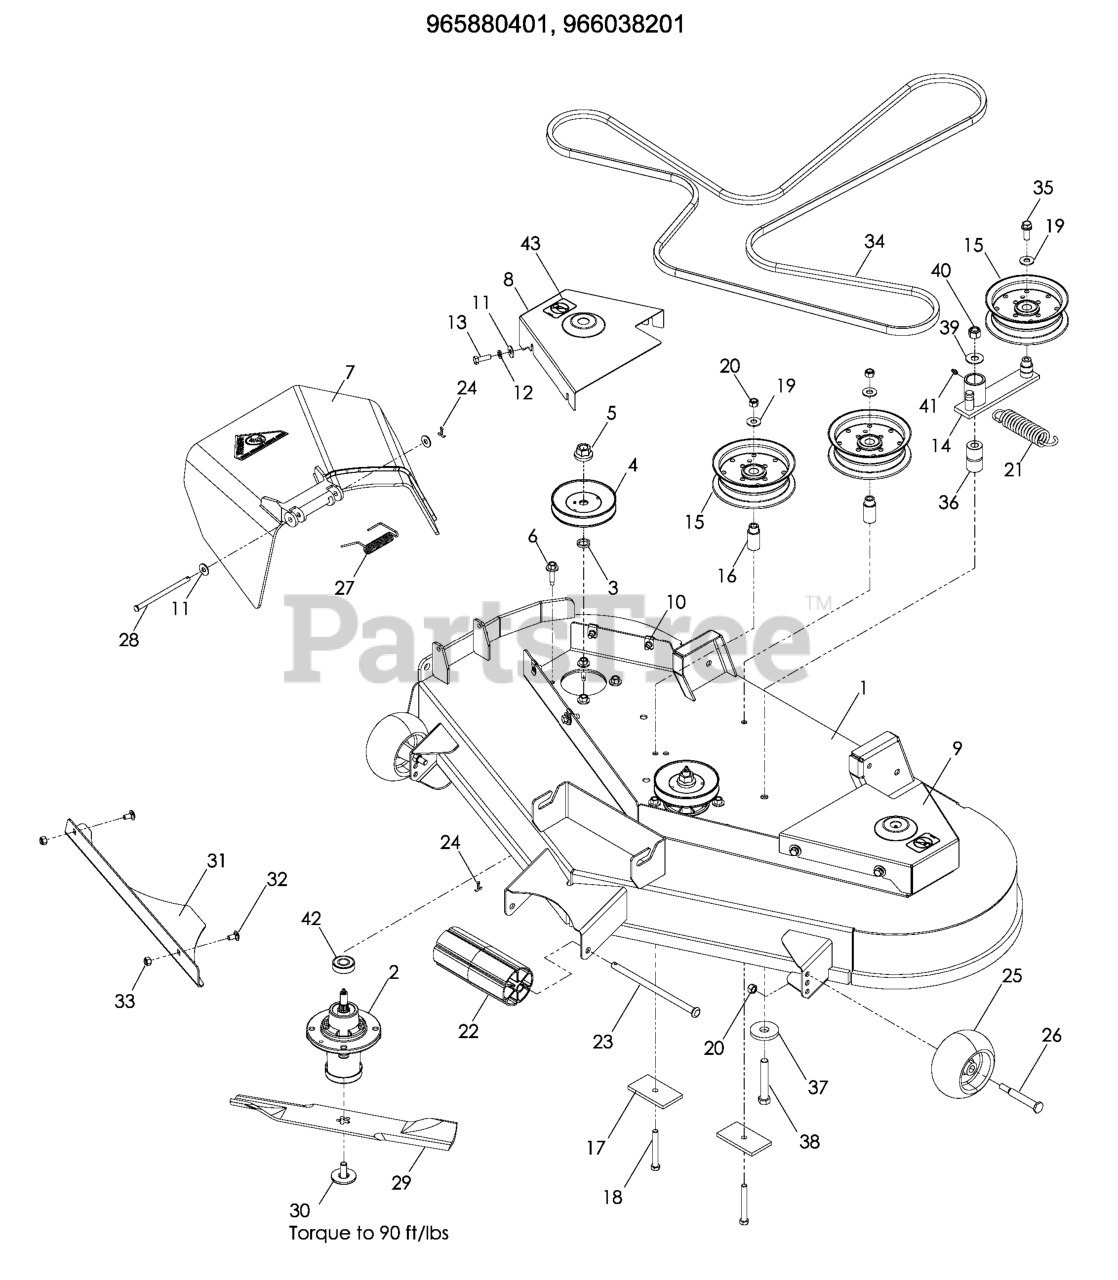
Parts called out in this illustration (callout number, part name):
1	DECK.48".TRI-FORCE.W/DECALS.OR
2	MANDREL.DECK.ASSEMBLY
3	WASHER-SPACER
4	PULLEY MANDREL
5	LOCKNUT - 9/16
6	WASHER HEAD SCREW
7	DISCHARGE CHUTE 48"
8	BELT SHIELD - R.H. ORANGE
9	BELT SHIELD - L.H. ORANGE
10	U-CLIP 5/16-18 NUT RETAINER
11	WASHER 5/16 FLAT
12	WASHER.LOCK.HVY.HLCL.SPR.5/16
13	HCS 5/16C X 3/4
14	PULLEY - IDLER, NYLON
15	PULLEY, IDLER
16	IDLER BUSHING
17	SUPPORT PLATE
18	HCS 3/8C X 3
19	WASHER 3/8 FLAT
20	NUT 3/8-16 NYLOC
22	NOSE ROLLER 48"
23	NOSE ROLLER ROD
24	RP_COTTER PIN 1/8 X 3/4
25	GAUGE WHEEL
26	SHOULDER BOLT 1/2X2-5/8 ZD SPE
27	SPRING - TORSION
28	PIN-CLEVIS 5/16 DIA X 5.19 ZD
29	BLADE, 16-1/4"
30	BLADE BOLT ASSY-7/16" TB REPL
31	CONFINEMENT PLATE 48" BLK
32	CARRIAGE BOLT 5/16C X 5/8"
33	NUT 5/16 NYLOC
34	BELT, DECK
35	4CS 3/8C X 1 SERRATED HEAD
36	PIVOT BUSHING
37	WASHER, SUPPORT
38	HCS 1/2C X 3 1/4
39	WASHER 1/2 FLAT
40	NUT 1/2-13 HEX NYLOC ZD
41	ZERK
42	BEARING, BALL
43	DECAL, NO STEP
